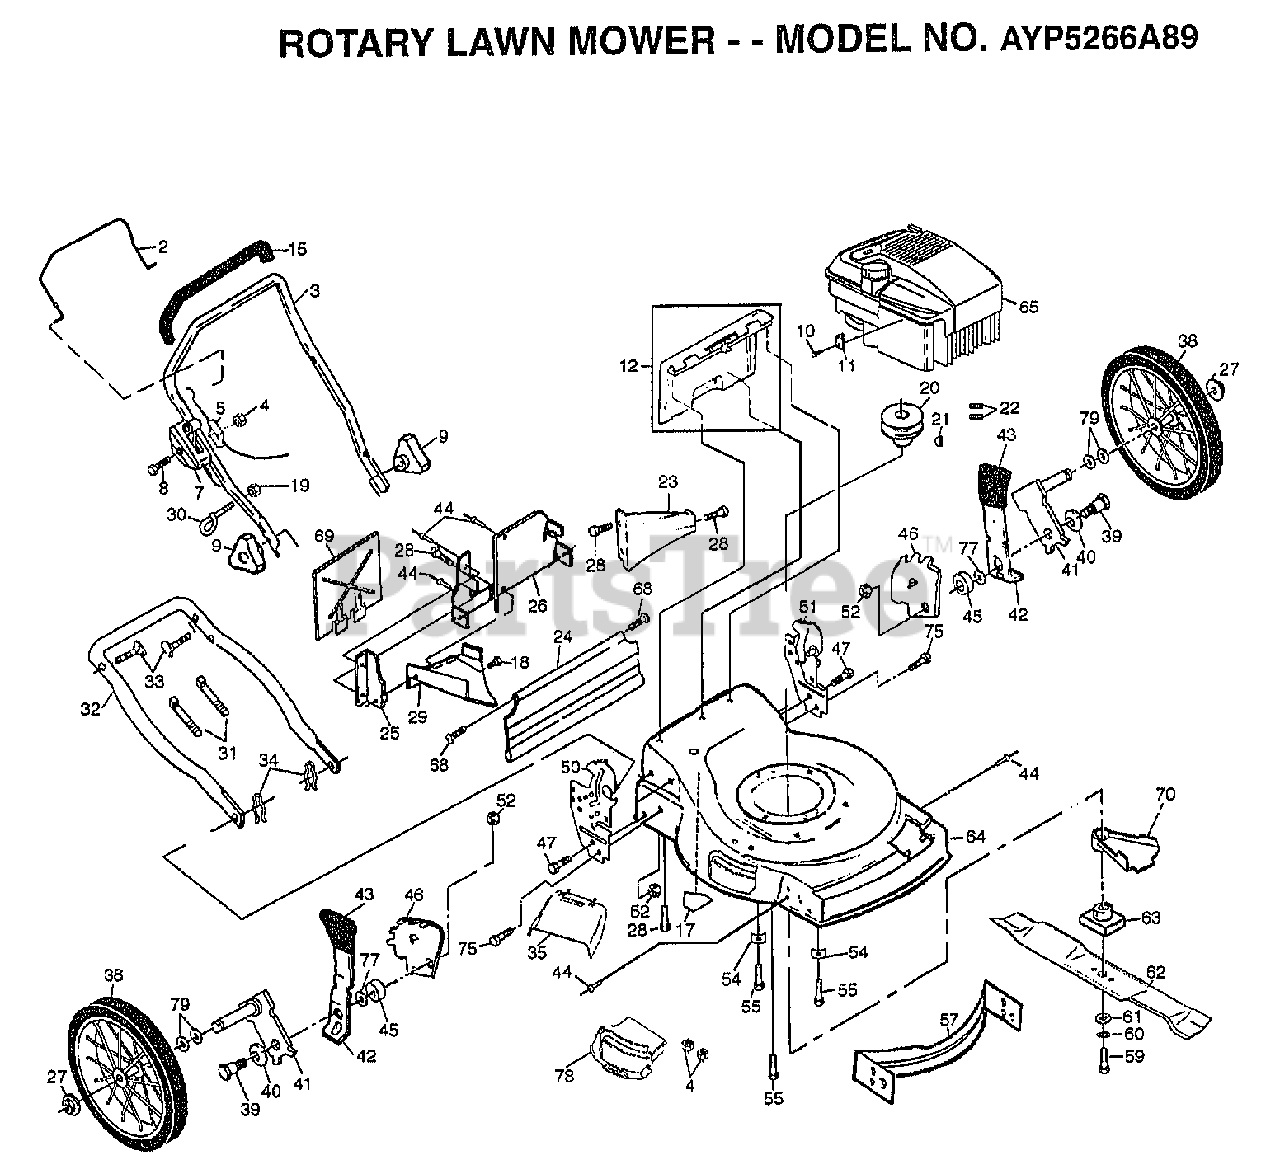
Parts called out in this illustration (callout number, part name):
2	BAIL.CNTRL.SRD.CM
5	"CABLE,ENG ZONE CO"
7	"CONTROL, THROTTLE"
8	SCREW.HXHD.WASH.
9	KNOB PM
10	SCREW PM
11	CABLE CLAMP
12	KIT.DOOR.REAR
17	DECAL-DANGER PM
18	SCREW.HXTAP.10-24
20	ENGINE.PULLEY.FWG
21	HI PRO KEY PM
22	SCREW
23	REAR BAFFLE
24	SKIRT.REAR.FGD.22
26	BACK PLATE
27	HEX FLANGE LOCKNT
28	SCREW
29	DISCHARGE BAFFLE
30	ROPE GUIDE
32	HANDLE LOWER
33	BOLT.HANDLE.LM
34	HAIRPIN COTTER
35	GUARD.DISCH.CLIPO
38	ASM WHL & TIRE
39	BOLT SHLD 3/8-16
41	AXLE ARM ASSY R
42	SPRING SELECTOR
43	KNOB PM
44	BLIND RIVET
45	SPACER.HEIGHT.ADJ
46	BRACKET.ADJ.9POS.
47	SCREW.HXWS.5/16
50	HANDLE BRKT ASY R
51	HANDLE BRKT ASY L
52	LOCKNUT PM
55	BOLT.ENG.3/8-16
57	KIT.BAF.FRT.22RD
59	SCREW
60	LOCKWASHER
61	"WASHER,HARDEN"
62	"BLADE.MULCH.22"""
63	ADAPTOR.BLADE.LM
64	LAWNMOWER ASM KIT
68	HINGE SCREW
69	MULCHER PLATE
77	WASHER PM
78	KIT.DOOR.MUL.CO
79	WAVE WASHER
